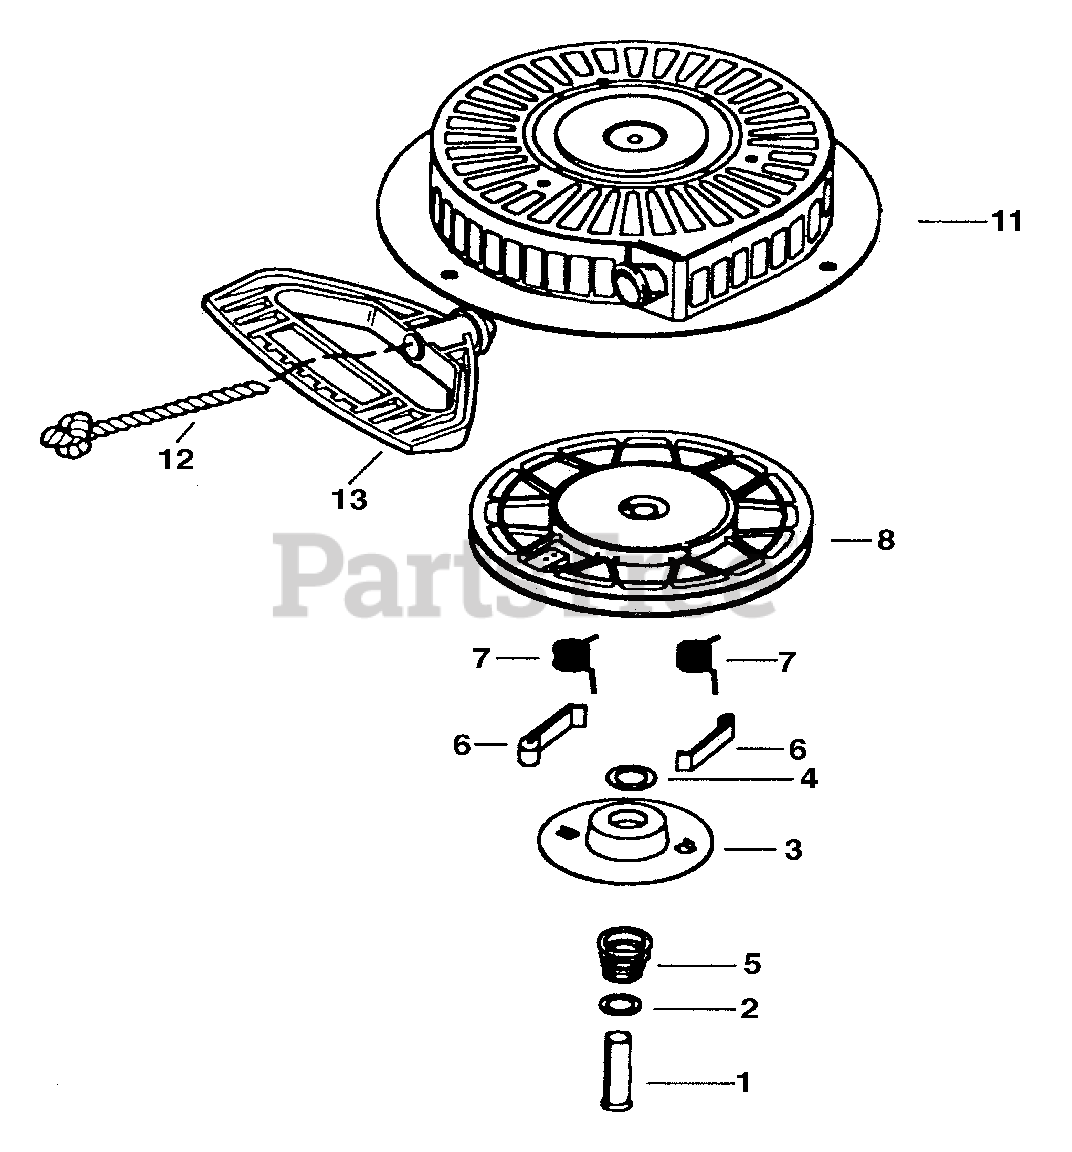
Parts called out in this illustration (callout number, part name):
1	Spring Pin
3	Retainer
5	Brake Spring
6	Starter Dog
7	Dog Spring
8	Pulley & Rewind Spring Ass'y.
11	Starter Housing Ass'y.
12	Starter Rope (Length 98" x 9/64" Dia.)
13	Mitten Grip Handle (Not
